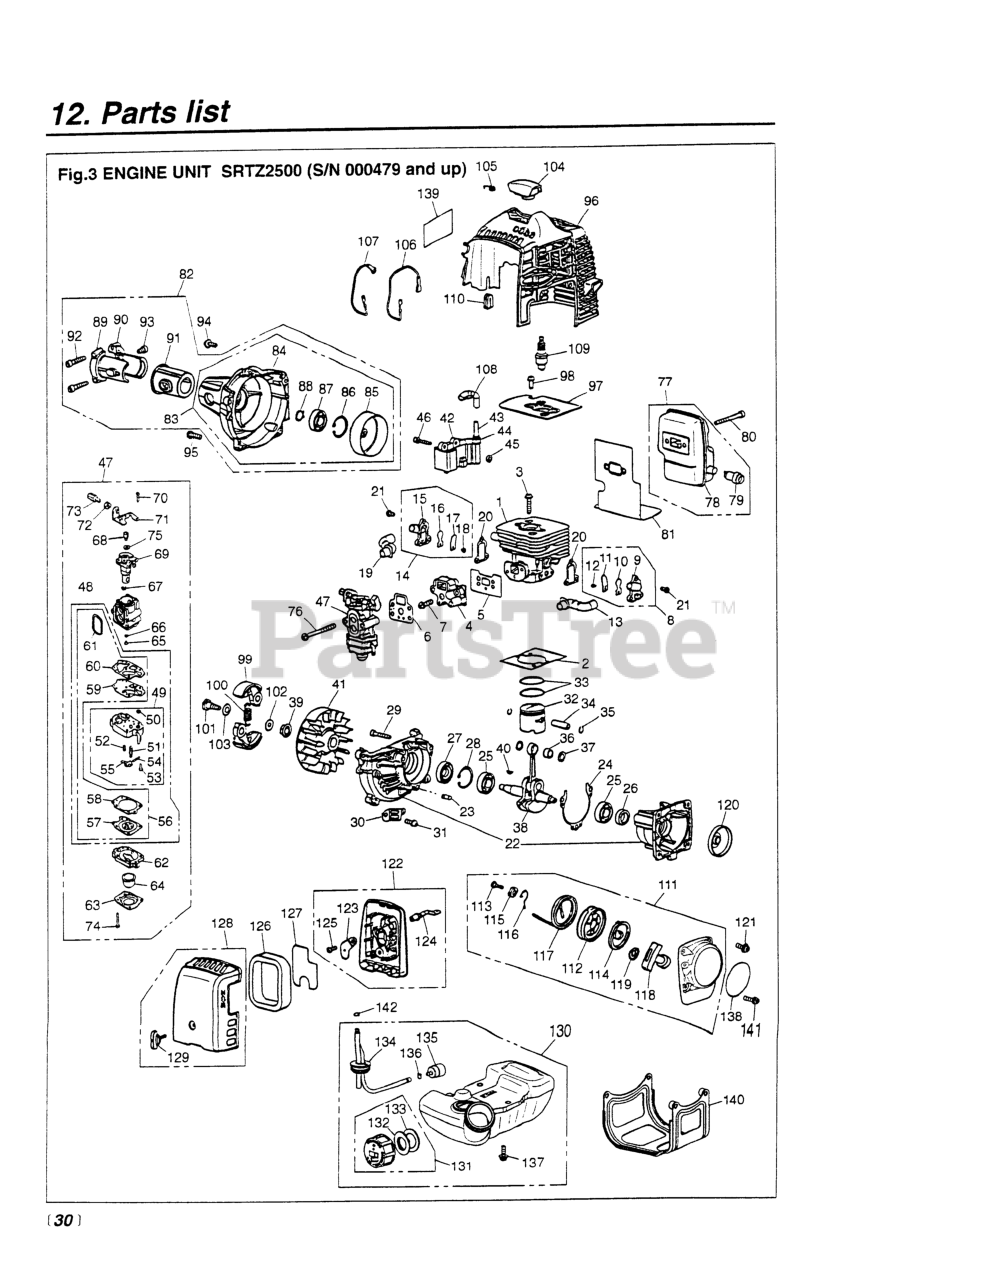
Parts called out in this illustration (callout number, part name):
1	CYLINDER (RPLS -12110)
2	GASKET, BASE
3	BOLT, M5 X 22
4	(REPLACES -13160)(USE -13162)
5	GASKET, INSULATOR
6	GASKET, CARBURETOR
9	CASE VALVE
10	VALVE, REED
11	STOPPER
12	SCREW, M3 x 8
13	PIPE, AIR
16	VALVE, REED
17	STOPPER
18	SCREW, M3 x 8
19	PIPE, AIR (F)
20	GASKET, VALVE
21	SCREW
22	CRANKCASE COMP (USE 4810-21101
23	PIN
24	GASKET
25	BEARING
26	SEAL
27	SEAL, OIL (RPLS 1140-21220)
28	RING, SNAP, M28 x 1.2
29	BOLT, M5 X 30
32	PISTON
33	RING, PISTON
34	PIN, PISTON
35	RING, SNAP (RPLS 1101-41320)
37	WASHER
38	CRANKSHAFT COMPLETE
40	KEY
41	ROTOR
42	COIL-A
43	CORD
44	CAP
45	SPACER (RPLS -71260)
46	BOLT, M4 x 22
49	PUMP BODY ASSEMBLY
50	SCREEN
51	VALVE, INLET
53	SCREW
54	PIN
55	LEVER
57	DIAPHRAGM
58	GASKET
59	DIAPHRAGM
60	GASKET, PUMP
61	RING
62	BODY, PURGE
63	COVER, PUMP
64	PUMP, PRIMING
65	JET (USE -81251)
66	RING, O
67	RING
68	SWIVEL
69	VALVE ASSY
70	SCREW
72	NUT, CABLE ADJUSTER
73	SCREW, CABLE ADJUSTER
74	SCREW
75	WASHER
77	MUFFLER ASSEMBLY
78	MUFFLER (REPLACES -15110)
79	ARRESTER
80	BOLT, M5 x 50
84	COVER, FAN (USE -31111)
86	RING, SNAP, M28 x 1.2
87	BEARING
88	RING, SNAP (RPLS 3130-13270)
89	BRACKET (A) (RPLS -31210)
90	BRACKET (B) (REPLACES -31220)
91	CUSHION
92	BOLT, M5 X 30
93	BOLT (USE 3310-31720)
94	SCREW
96	COVER, ENGINE (RPLS -32110)
97	PLATE
99	SHOE (RPLS 1100-51114)
100	SPRING
101	BOLT
102	WASHER, FLAT (USE 182303)
105	SPRING
106	CORD (BLACK)
107	CORD, EARTH (RED)
110	GROMMET
111	RECOIL ASSEMBLY
112	REEL
113	SCREW
114	SPRING, SPIRAL
115	COLLAR
116	ARM
117	ROPE (REPLACES 4500-75160)
118	KNOB (RPLS -75420)
119	PLATE, STOPPER
120	PULLEY
121	SCREW
122	BODY ASSEMBLY
123	PLATE, CHOKE
124	LEVER, CHOKE
125	SCREW (REPLACES 50030272)
126	ELEMENT
127	SCREEN
128	COVER ASSEMBLY
129	KNOB (RPLS -82220)
130	TANK ASSY (USE -87001)
132	HOLDER (REPLACES -85230)
133	PACKING
134	PIPE COMPLETE
135	FILTER (RPLS 1850-85300)
136	CLIP (REPLACES 2841-31280)
137	SCREW
138	LABEL, RECOIL
139	LABEL, COVER (RPLS -31130)
142	CLIP
